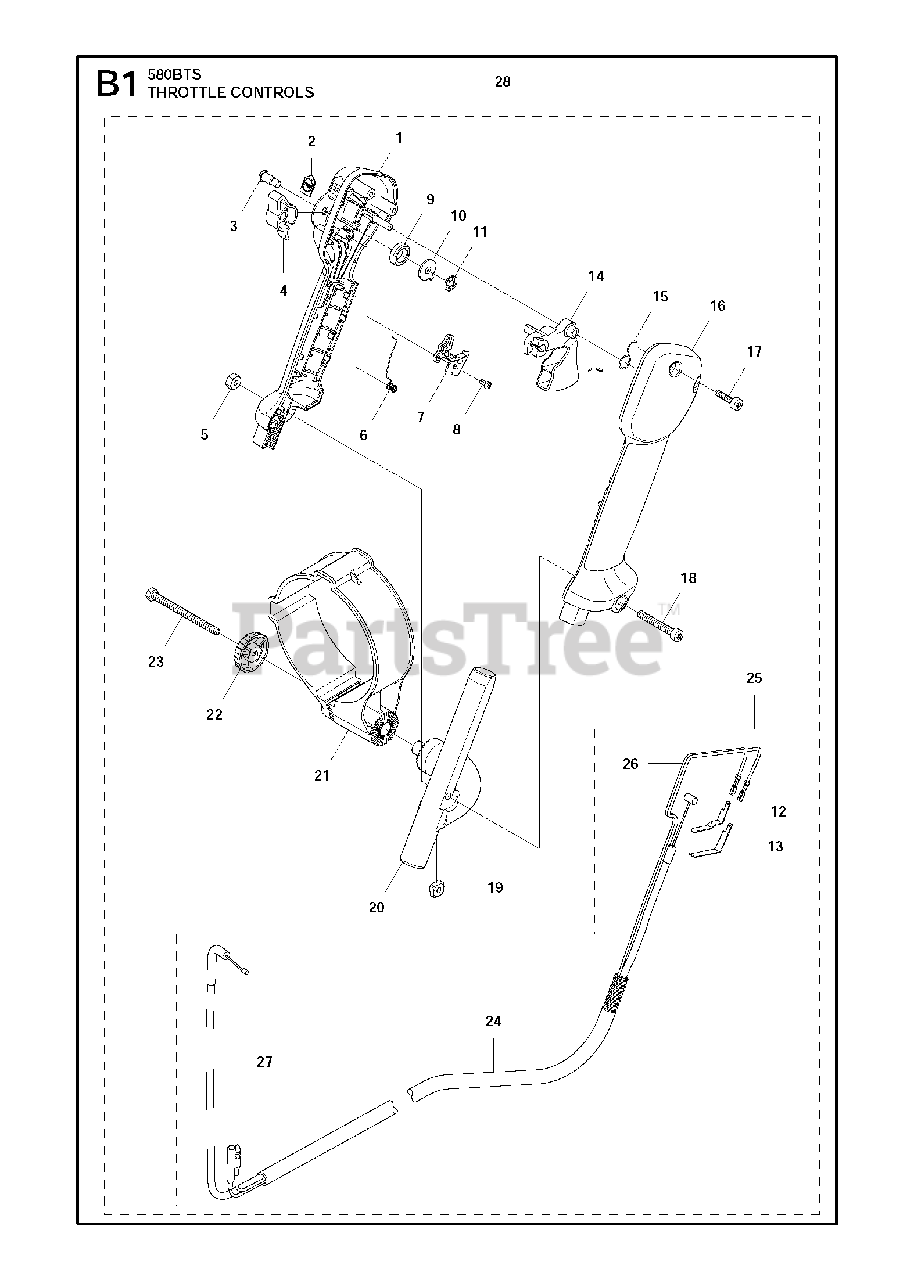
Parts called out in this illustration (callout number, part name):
1	HANDLE HALF (L)
2	PLATE
3	SHAFT PIVOT
4	LEVER STOP
5	NUT
6	SPRING
7	RETAINER
8	SCREW
9	SPRING RUBBER
10	WASHER
11	CLIP
12	CONTACT SPRING
13	CONTACT SPRING
14	TRIGGER 848L5W34C0
15	SPRING
16	HANDLE HALF (R)
17	SCREW
18	SCREW
19	SQUARE NUT M5
20	HOLDER, HANDLE
21	HANDLE HOLDER
22	KNOB
23	SCREW
24	TUBE
25	WIRING ASSY
26	CORD COMPLETE
27	CABLE, COMP
28	ASSY LEVER SET
